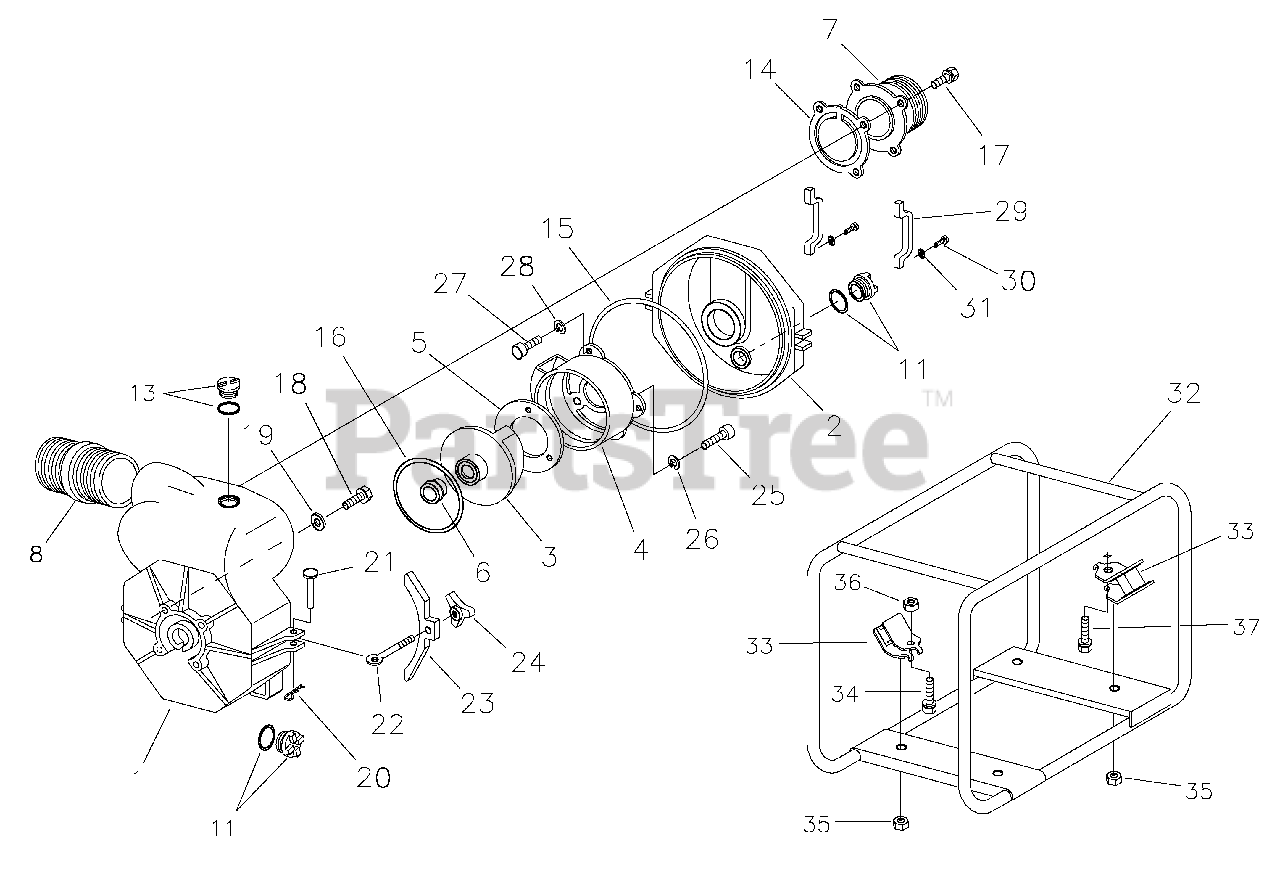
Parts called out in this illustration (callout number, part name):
6	Seal, Mechanical
7	Valve Case, BSP, 3"
8	Fitting, Pipe, BSP, 3"
13	Assy, Priming Plug
17	Hex Bolt, M10 x 30
18	Flange Bolt, 5/16 x 48
23	Casing Cover Holder
25	Hex Socket Bolt, M6 x 16
26	Lock Washer, M6
27	Hex Socket Bolt, M8 x 20
28	Lock Washer, M8
29	Drain Cover Handle
30	Hex Bolt, M6 x 25
31	Washer, M6
33	Anti Vibration, Rubber
34	Hex Bolt, M10 x 40
35	Flange Nut, M8
36	Flange Nut, M10
37	Hex Bolt, M10 x 20
